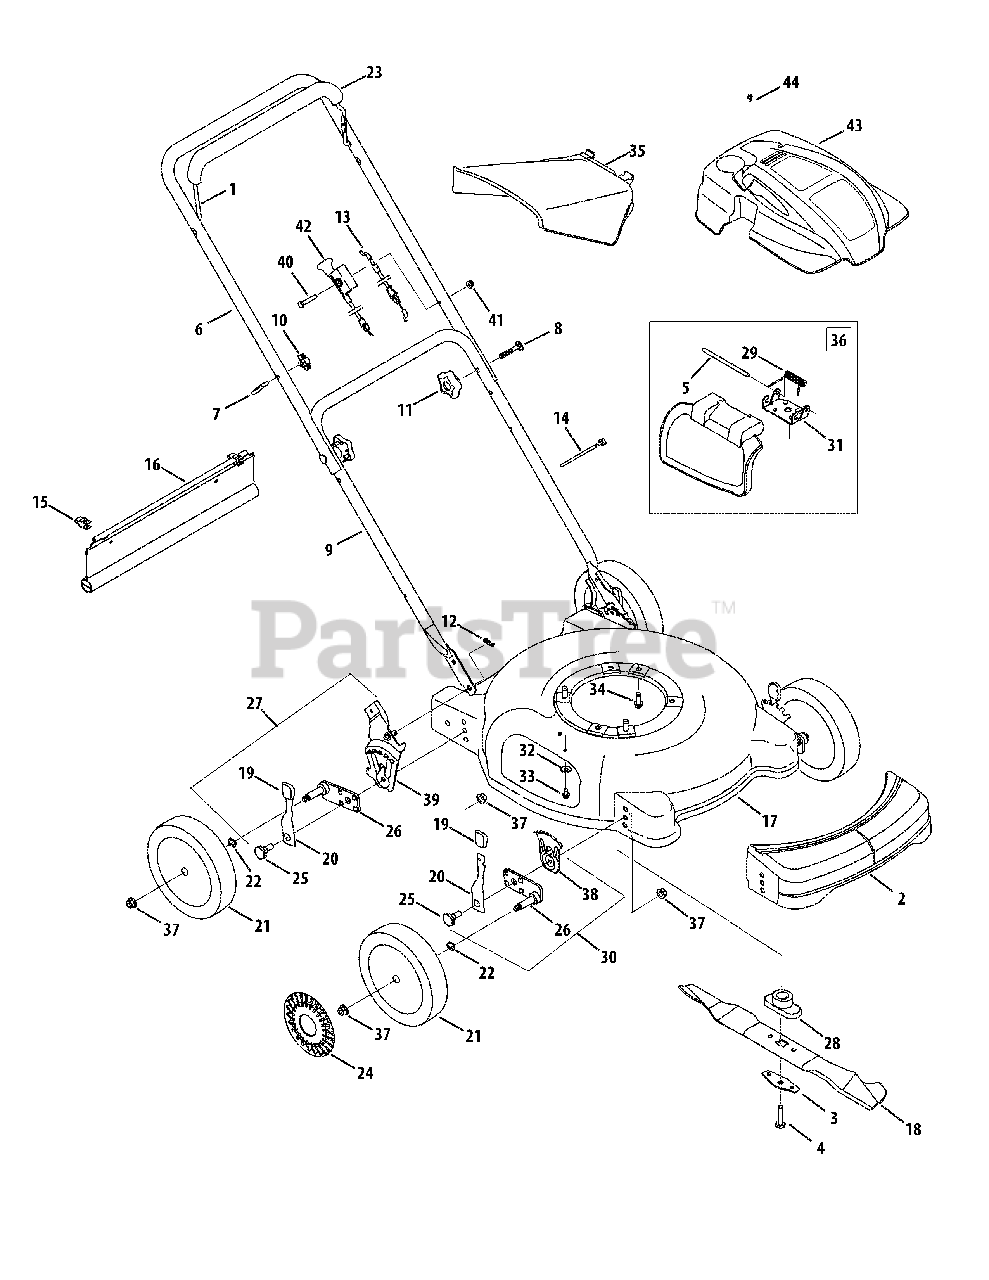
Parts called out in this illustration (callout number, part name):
2	Front Cover
3	Blade Bell Support
5	Hinge Pin
7	Rope Guide
8	Carriage Bolt
11	Star Knob
12	Hairpin Clip
13	Control Cable
14	Cable Tie
15	Hinge Clip
16	Trail Shield
19	Height Adjustment Knob
20	Spring Lever
21	Wheel Assembly
22	Wave Washer
23	Bail Cover
24	Hubcap
25	Shoulder Bolt
26	Pivot Arm Assembly - RH Front
26	Pivot Arm Assembly - LH Rear
26	Pivot Arm Assembly - LH Front
26	Pivot Arm Assembly - RH Rear
27	Handle Bracket Assembly RH
27	Handle Bracket Assembly LH
28	Blade Adapter
29	Torsion Spring
30	Height Adjust. Assembly LH
30	Height Adjust. Assembly RH
32	Bell Washer
33	Hex Washer Hd. TT Screw
34	TT Sems Screw
35	Chute Deflector
36	Mulching Plug Assembly
37	Hex Lock Nut
38	Height Adjustment Plate
40	Screw, 1/4-20 x 1.50
41	Nut, Flange Lock, 1/4-20
42	Choke Cable
43	Engine Shroud
44	Screw, Machine, M4-.7
